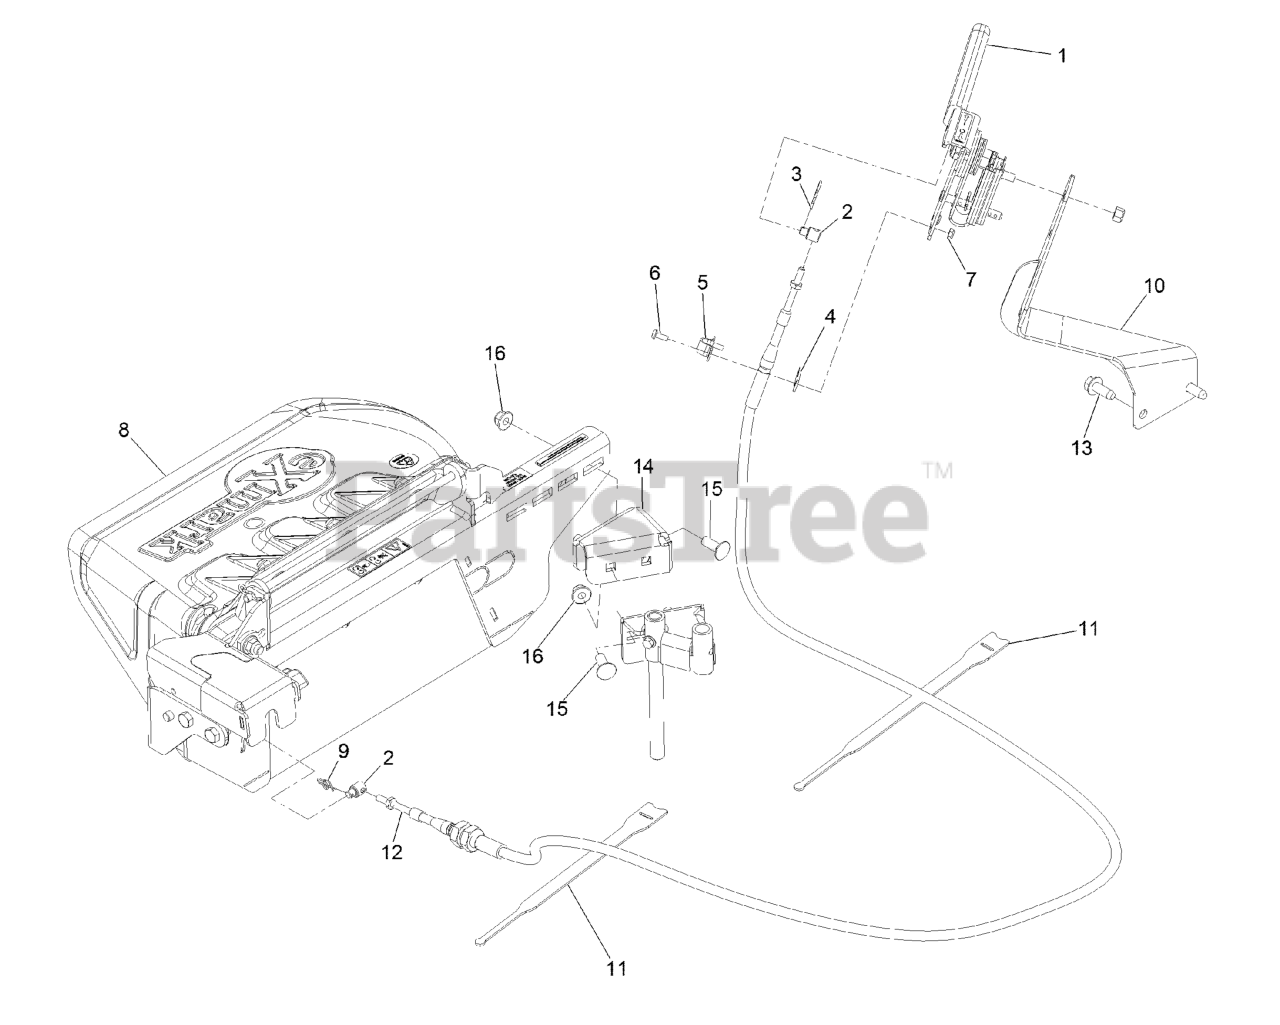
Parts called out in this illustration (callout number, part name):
1	ASM, HAND LEVER
2	PIVOT, CONTROL CABLE
3	PIN-COTTER
4	SHIM,CONTROL CABLE
6	SCREW-PPH
7	NUT-LOCK, NI
8	ASM, OCD
9	PIN-COTTER, LOCKING
10	Mount-Handle Ocdc
11	STRAP-VELCRO, CABLE TIE
12	CABLE-DISCHARGE GATE
13	SCREW-FORMING, THREAD
14	BRACKET-OCD
15	SCREW-CARR
16	NUT-HF, NI
